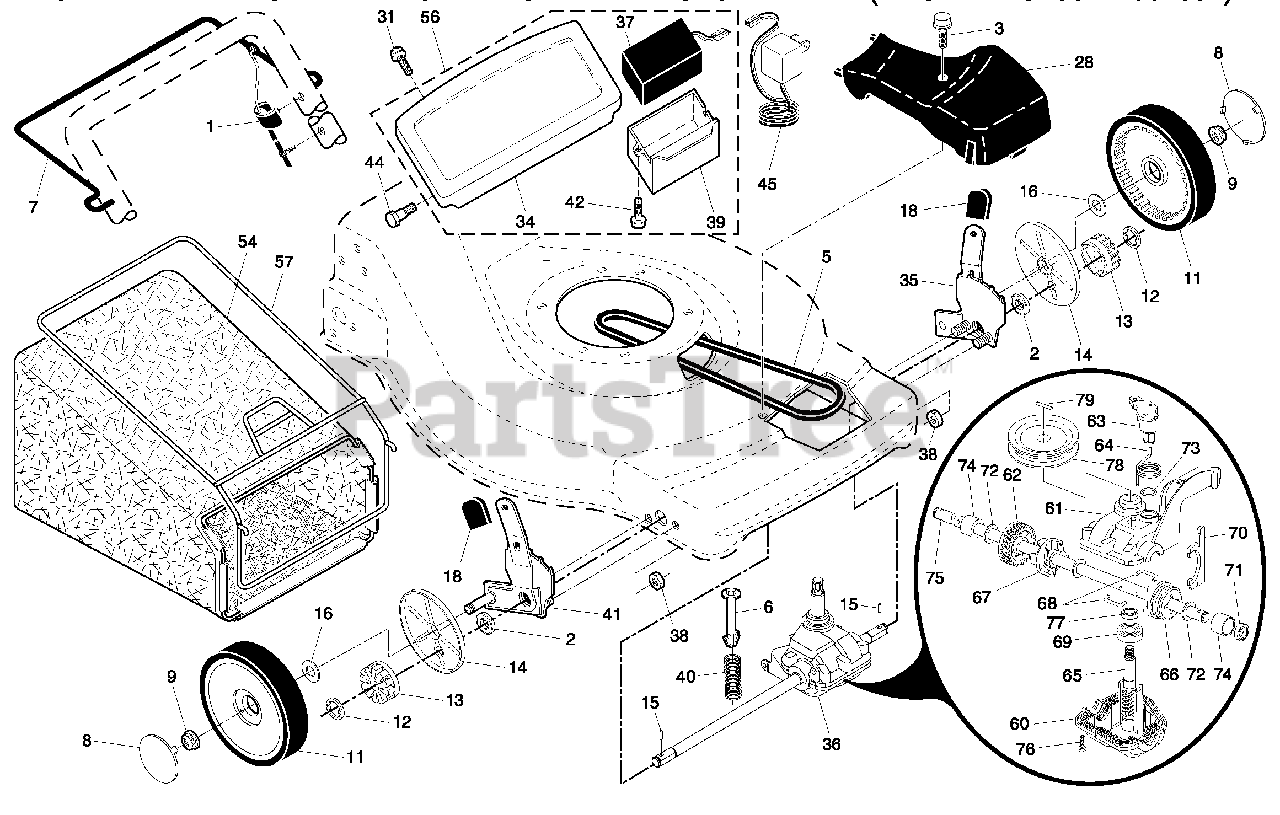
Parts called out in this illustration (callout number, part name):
1	Drive Control Assembly
2	Bearing, Wheel Adjuster
3	Pan Head Tapping Screw #10-24 x 2-3/4
6	Retainer, Spring
7	Bar, Drive Control
8	Hubcap
9	Locknut, Hex
11	Wheel & Tire Assembly, Front
12	E-Ring
13	Pinion
14	Dust Cover
15	Pawl, Drive
16	Washer, Flat 3/8
18	Selector Knob
28	Drive Cover
31	Screw, Trimplate
34	Trimplate
35	Kit, Wheel Adjuster, LH
36	Gear Case Assembly, Complete
37	Battery
38	Locknut 1/4-20
39	Battery Box
40	Spring
41	Kit, Wheel Adjuster, RH
42	Screw, Battery Box
44	Screw, Trimplate
45	Charger, Battery
54	Grassbag Assembly
56	Trimplate, Battery Box and Battery Assembly
57	Frame, Grassbag
60	Case, Lower
61	Case, Upper
62	Gear, 27 Teeth
63	Lever, Clutch
64	Spring, Return
65	Shaft, Input
66	Dog, Movable
67	Dog, Fixed
68	Wire, Formed
69	Bearing, Ball
70	Fork, Shift
71	Seal, Output Shaft
72	Washer
73	Seal, Case
74	Bushing
75	Shaft, Output
76	Screw
77	Seal, Input Shaft
78	Pulley, Drive
79	Pin, Retainer
